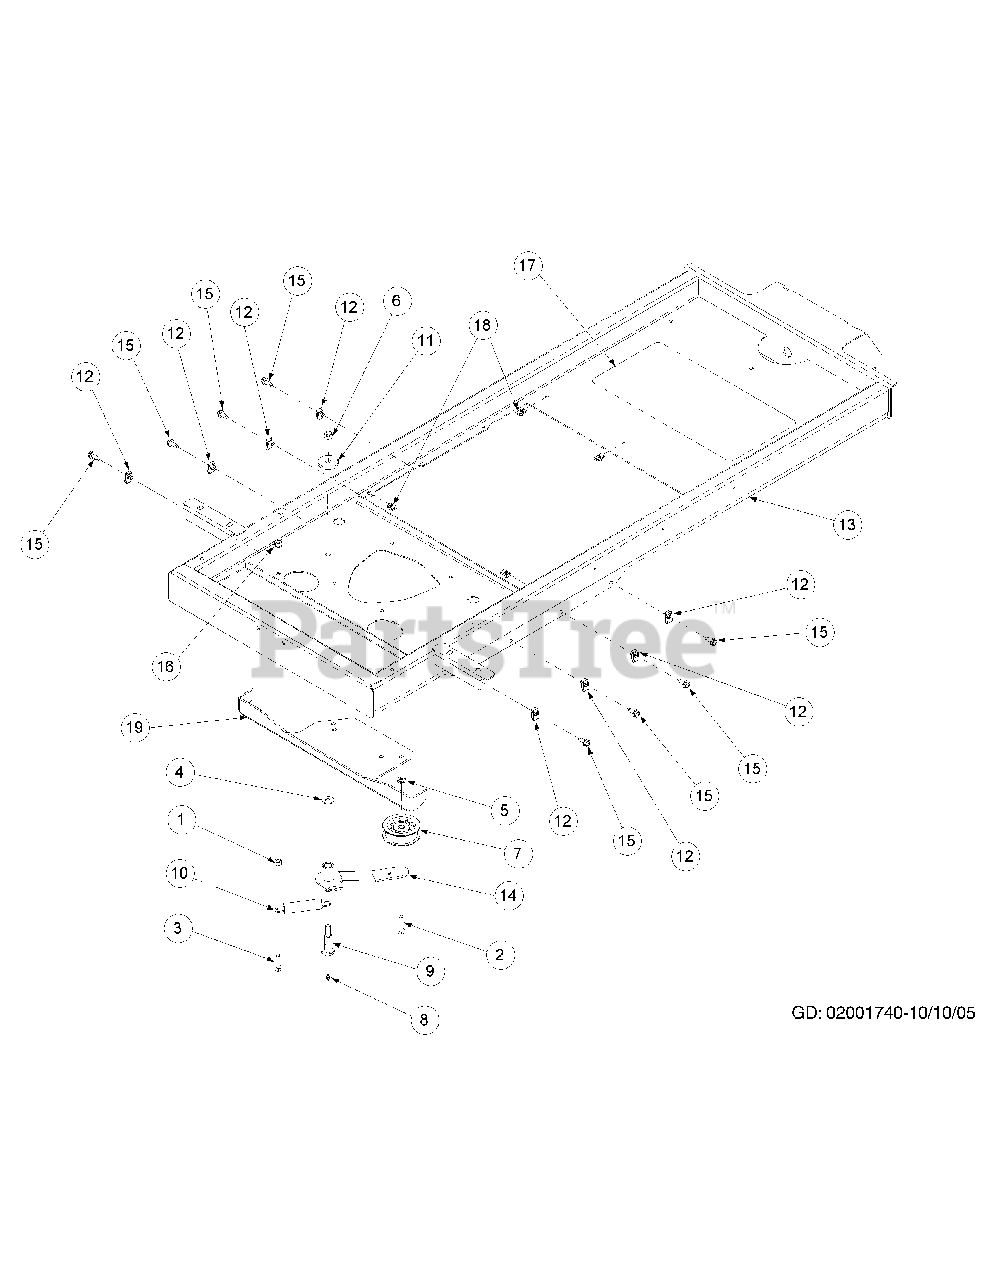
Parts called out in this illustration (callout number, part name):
1	Hex Nut, 5/16-18
2	Hex Cap Screw, 3/8-16 x 1-1/2
3	Hex Cap Screw, 5/16-18 x 1-1/4
4	Flat Washer, 3/8 zinc
5	Hex Nut, 3/8-16 Flange Lock
6	Nylock Nut, 7/16-14
7	Flat Idler Pully w/ adaptor
8	Grease Fitting, 1/4-28 x 3/16
9	Shoulder Bolt
10	Extension Spring, .865 OD x 4.68 lg
11	Flat Washer, 7/16 ID x 1.75 OD
12	U-Nut, 5/16-18
13	Frame Assembly Weldment
14	Idler Arm Assembly
15	Hex Washer Screw 5/16-18 x .750
16	Nut, 5/16-18, Hexflange Lock
17	Abrasive Foot Pad
18	U-Nut, 1/4-20
19	Engine Plate Stiffener
